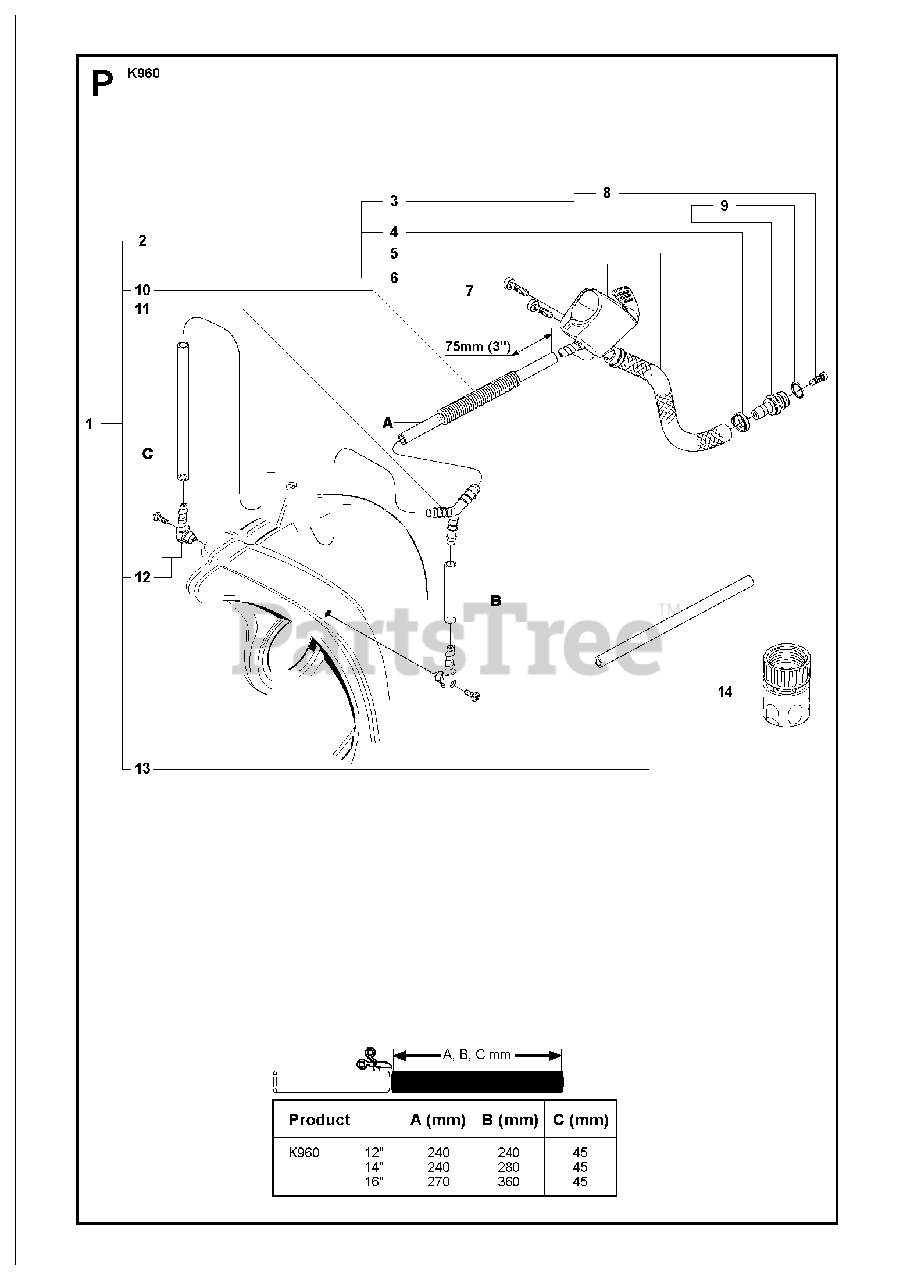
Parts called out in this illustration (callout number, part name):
1	HOSE KIT"12"", 14"". Incl. 2, 10 - 13"
1	HOSE KIT"16"". Incl. 2, 11 - 13"
2	HOSE ASSYIncl. 3 - 6
3	NIPPLEIncl. 7
4	HOSE CLAMP
5	HOSEL=230 mm
6	VALVE ASSYIncl. 7
7	SCREW ITXSCT
8	FILTERIncl. 9
9	O-RING
10	PROTECTIVE SPRING"16"" only"
13	HOSE800 mm
14	COUPLER
